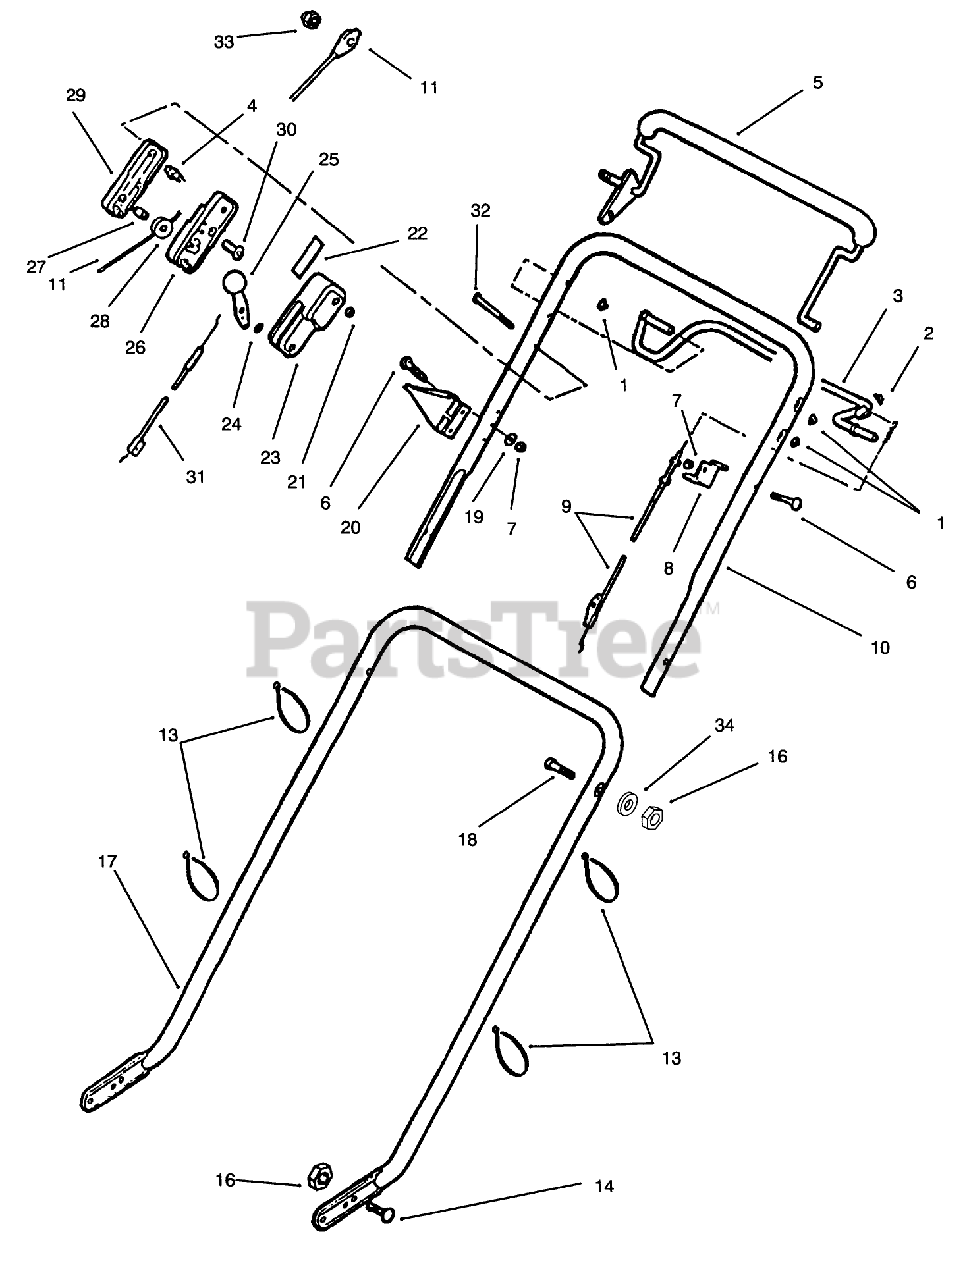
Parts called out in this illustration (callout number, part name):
5	CONTROL LEVER ARG
7	NUT-LOCK, NI
8	ANCHOR C'DUIT TRO
9	CABLE - CONTROL
11	CONTROL CABLE
13	TIE-CABLE
16	NUT-LOCK, NI
21	NUT C/LOCK E
24	WASHER-SPRING
25	LEVER&KNOB AY WES
27	PIN SKF
28	PULLEY PL
29	OUTER CONTROL CASE
31	CABLE TH'TTLE WES
33	NUT ACORN
34	WASHER-CURVED
